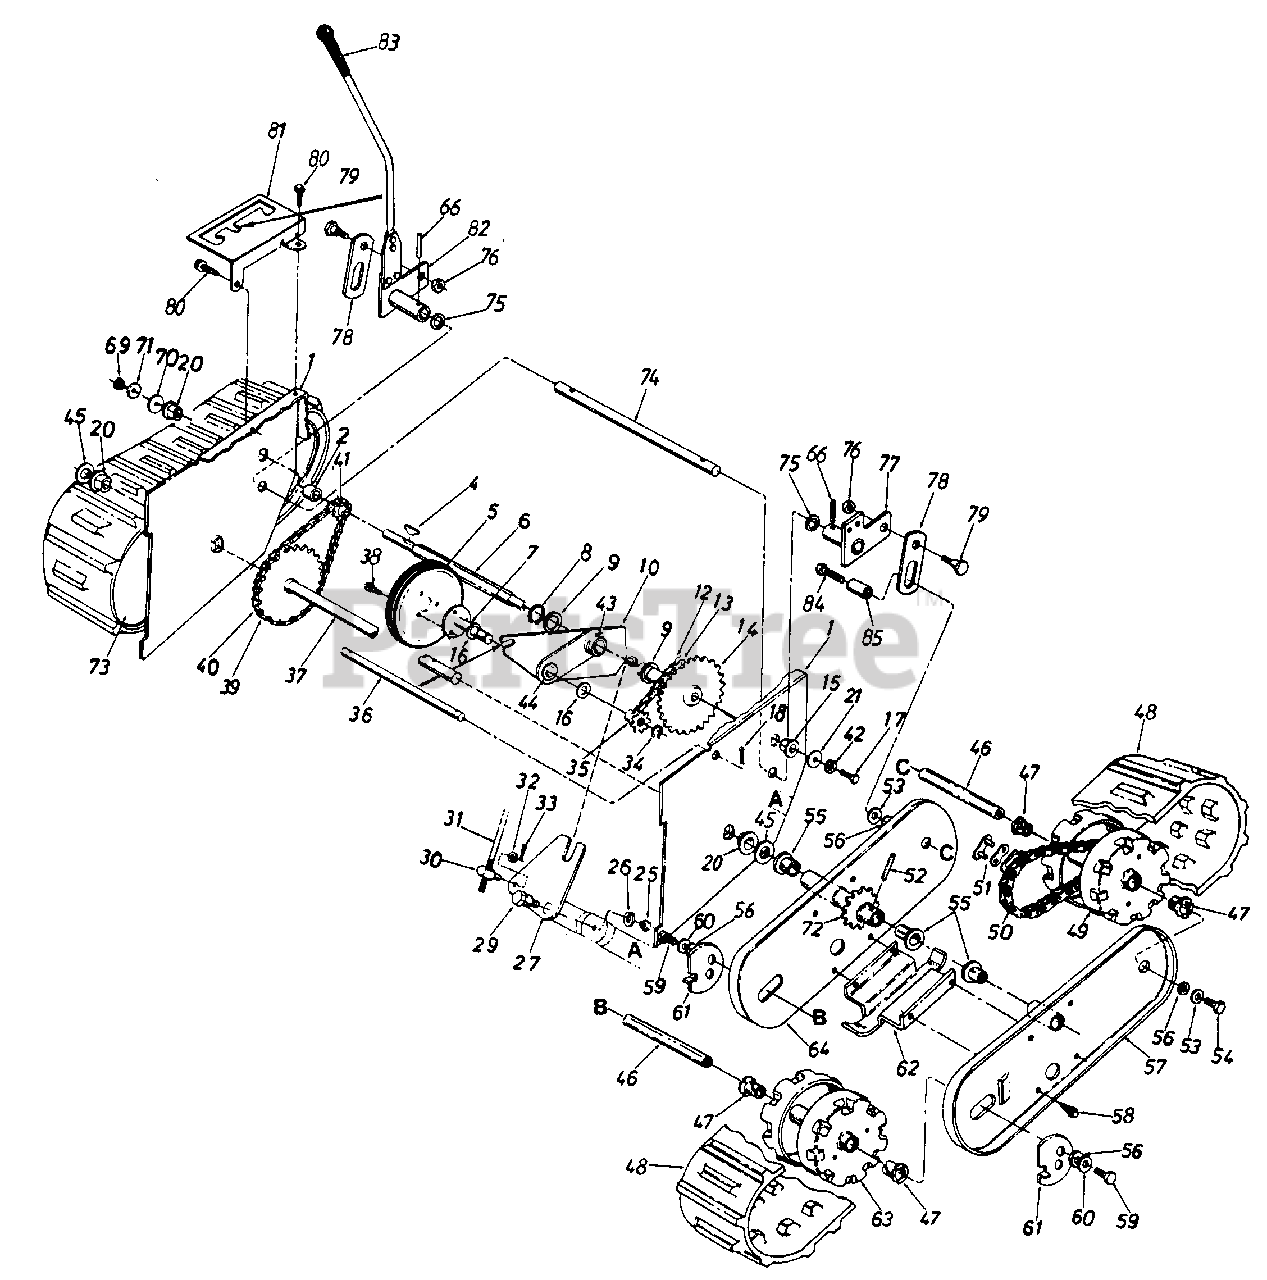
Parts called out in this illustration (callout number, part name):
1	FRAME ASSY
4	KEY-HI-PRO #4-3/32X5/8 DIA-HDN
5	WHEEL ASSY-FRICTION
6	SHAFT-HEX
7	PLATE ASSY-FRICTION WHEEL MTG
8	RING-SNAP FOR 1.00 DIA SHAFT
9	WASHER-FL-1.03 ID X 1.62 X .03 HD
10	BRACKET ASSY-SLIDING
12	#41 CHAIN 1/2" PITCH X 35 LINKS
13	#41 MASTER LINK 1/2 PITCH TYPEII
14	SPROCKET ASSY-32T
15	BEARING-FLANGE
16	WASHER-FL
17	SCREW-HEX 5/16-18 X .62
18	PIN-COTTER-3/32 DIA X .75
20	BEARING-FLANGE
21	WASHER-FL-.312 X 1.125 X .125
25	NUT-HEX JAM 3/8-18
26	WASHER-LOCK-3/8
27	BRACKET-LINKAGE
29	SCREW-SHLD .625 DIA X .163
30	FERRULE
31	ROD-SHIFT
32	WASHER-FL-.344 X .62
33	PIN-COTTER-3/32 DIA X .75
34	RING-C SNAP
35	SPROCKET-7T
37	AXLE ASSY-WHEEL
38	SCREW-HEX WASH SF TAPP
39	#420 CHAIN 1/2 PITCH X 39 LINKS
40	#420 MASTER LINK 1/2 PITCH TYPE II
41	SPROCKET-CENTER #41-8T
42	WASHER-LOCK-5/16
43	BEARING
44	BEARING-FLANGE .630 ID
45	WASHER-FL-.760ID X 1.49OD X .06HDN
46	SHAFT-WHEEL
47	BEARING-FLANGE
48	TRACK-SNOWTHROWER
49	WHEEL ASSY-DRIVE
50	#420 CHAIN 1/2 PITCH X 37 LINKS
51	#420 MASTER LINK 1/2 PITCH TYPE II
52	PIN-SPRING SPIRAL 1/4X1.5 HEAVY DT
53	WASHER-BELL .337 X .867 X .057
54	SCREW-HEX 5/16-24 X .62
55	BEARING-FLANGE
56	BEARING-FLANGE
57	PLATE ASSY-OUTER-LH
58	SCREW-HEX WASH SF TAPP
59	SCREW-HEX 5/16-24 X .62
60	WASHER-BELL .337 X .867 X .057
61	ADJUSTER-TRACK
62	SHOE-SKID
63	IDLER ASSY-WHEEL
64	PLATE ASSY-INNER-LH
66	PIN-SPRING-SPIR 1/4 X 1.250
69	NUT-HEX INS L-1/2-20
70	WASHER-FL-.546 X 1.28 X .090
71	WASHER-BELL .505 ID X 1.00 OD
72	SPROCKET ASSY-17T
73	PLATE ASSY-INNER-RH
74	AXLE-TRACK LOCK
75	WASHER-FL
76	NUT-HEX CENTER L-3/8-16
77	ARM ASSY-PIVOT-LH
78	LINK-SLOTTED
79	SCREW-SHLD
80	SCREW-HEX HD TAP
81	PLATE-POS SELECTOR
82	HANDLE ASSY-LOCK
84	SCREW-HEX 5/16-24 X 1.25
85	SPACER
